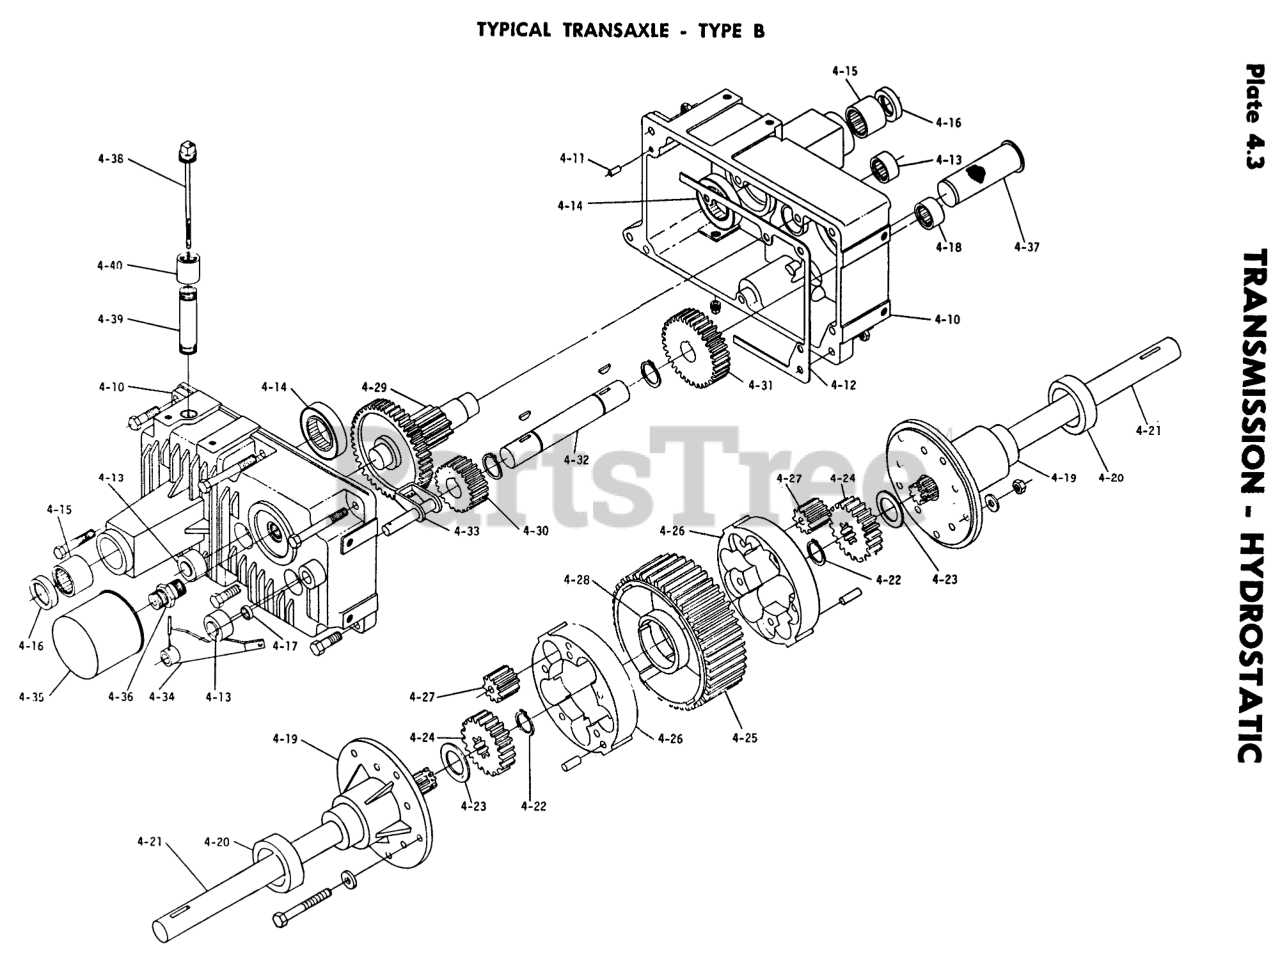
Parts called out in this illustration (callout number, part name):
4-10	Bolt Hex 3/8-16 x 5
4-10	Bolt Hex 3/8-16 x 1
4-10	Bolt 3/8-16 x 2 1/2
4-10	Bolt 3/8-16 x 2 1/4
4-11	PIN-DOWEL
4-13	BEARING-NEEDLE
4-16	SEAL-OIL
4-19	Bolt Hex 3 1/4
4-19	3/8-16 E.S.
4-19	Washer
4-24	SIDE GEAR
4-26	BULLT 252
4-32	Key
4-36	FITTING
4-39	Nipple 1/2 Pipe x 31/2
4-40	Coupling 1/2 Pipe
